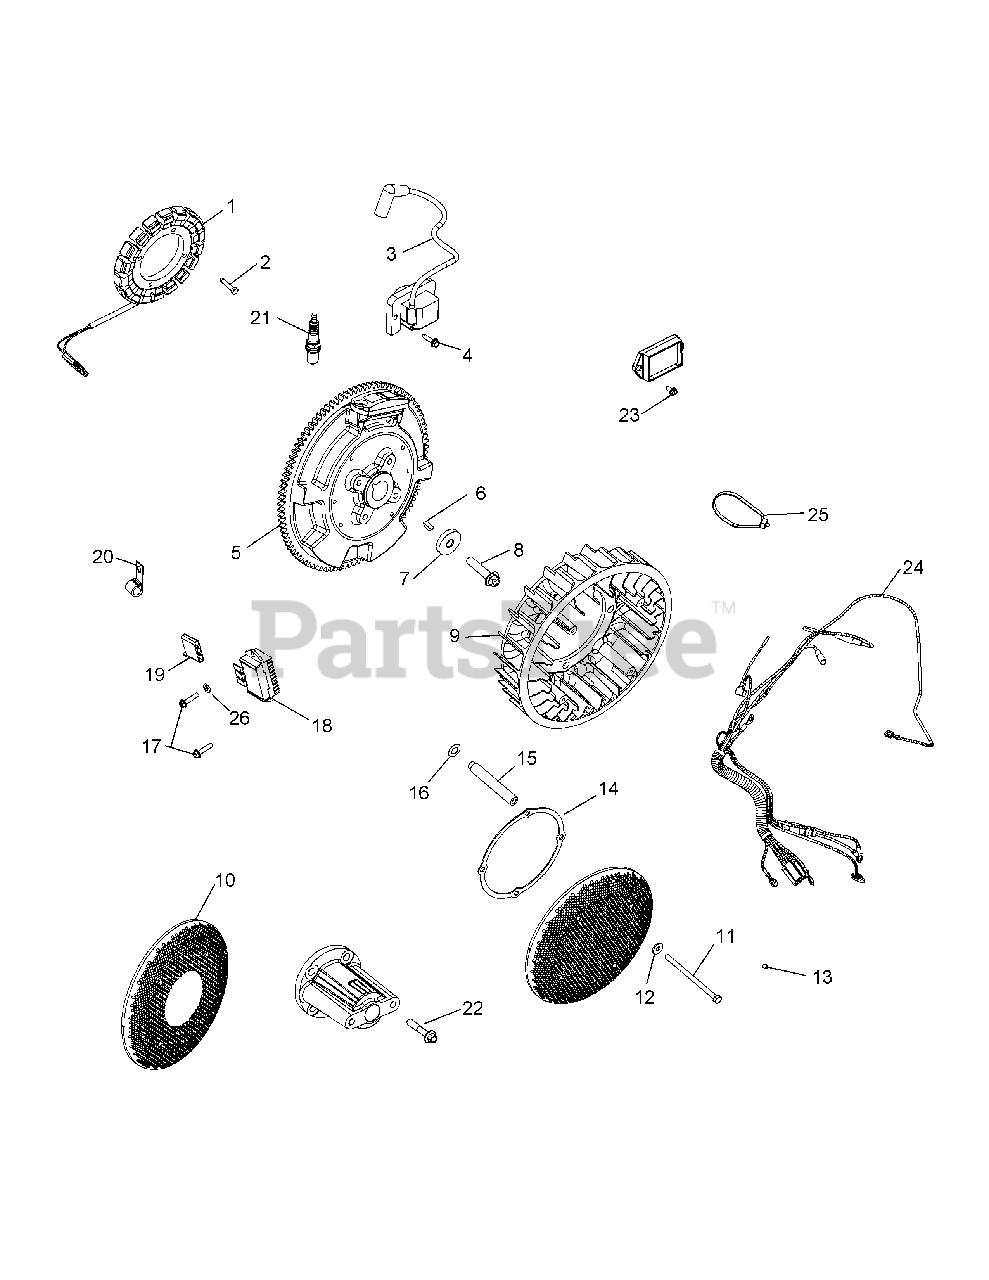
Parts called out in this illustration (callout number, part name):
1	Kit, 25 Amp Stator Assembly
1	Kit, 25 Amp Conversion
2	Thread Forming Screw
3	Module Ignition Key (CDI Fixed)
4	Thread Forming Screw
6	Key, 3/16 x 5/8
7	Flat Washer, 13/32
8	Flange Screw, M10 x 1.5 x 45
11	Cap Screw, M6 x 1.0 x 99.5
12	Flat Washer, 1/4 x 5/8
13	Set Screw, #10-24 X 1/4
14	Support Ring
16	Spring Washer, 10 MM
17	Hex Flange Hi-Lo Screw
18	Regulator/Rectifier
20	Cable Clip
21	Spark Plug (Std.)
22	Flange Screw, M8 x 1.25 x 45
23	Washer Head Tap Screw, #8-18 x 1/2
24	Wiring Harness Assembly
